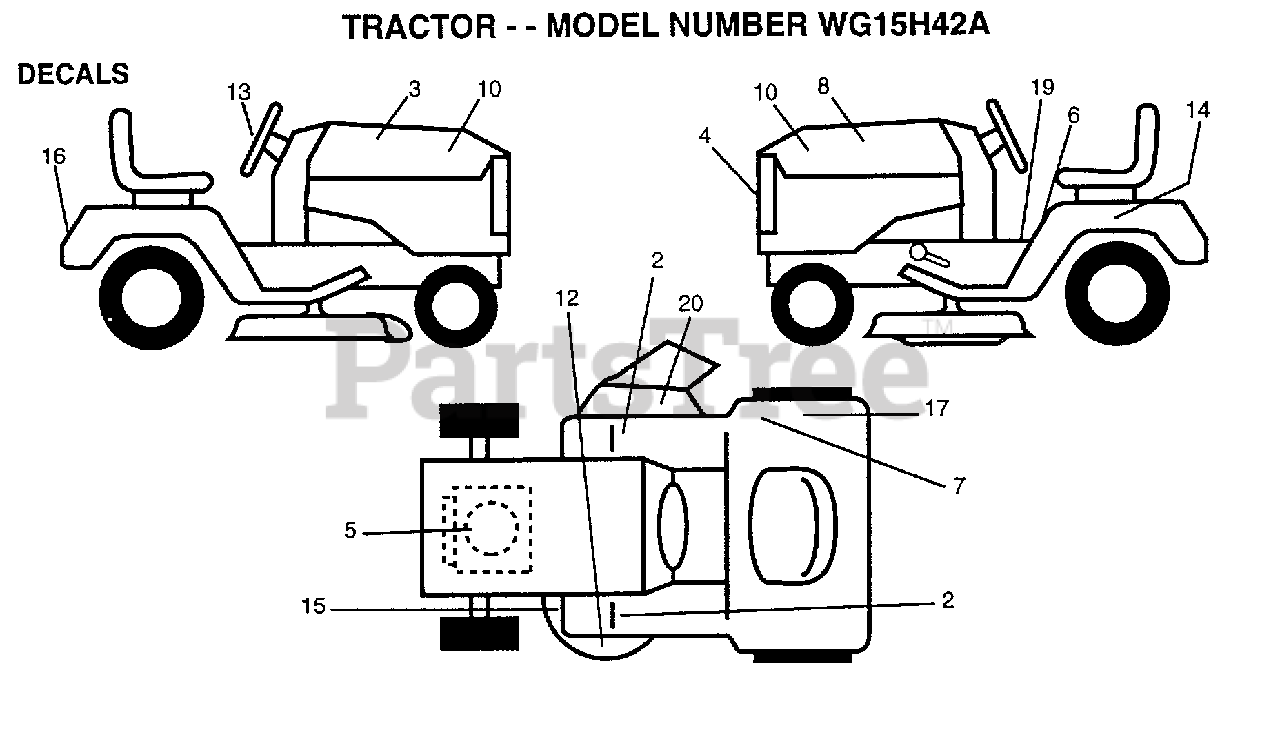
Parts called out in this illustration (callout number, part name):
2	"PAD,FOOTREST"
3	DECAL. HOOD RH
4	DECAL.GRILL
5	DECAL, ENGINE
6	DECAL.READ.O.MANU
7	DECAL.EURO.ST.CE.
8	DECAL HOOD LH
10	"DECAL PANEL,SIDE"
12	DECAL.MOWER
13	DECAL.WHL.STRG.
14	DECAL.BTRY.DANGER
15	DECAL
16	DECAL FENDER
19	DECAL BRAK PARK
20	DECAL.DANGER.CUTF
